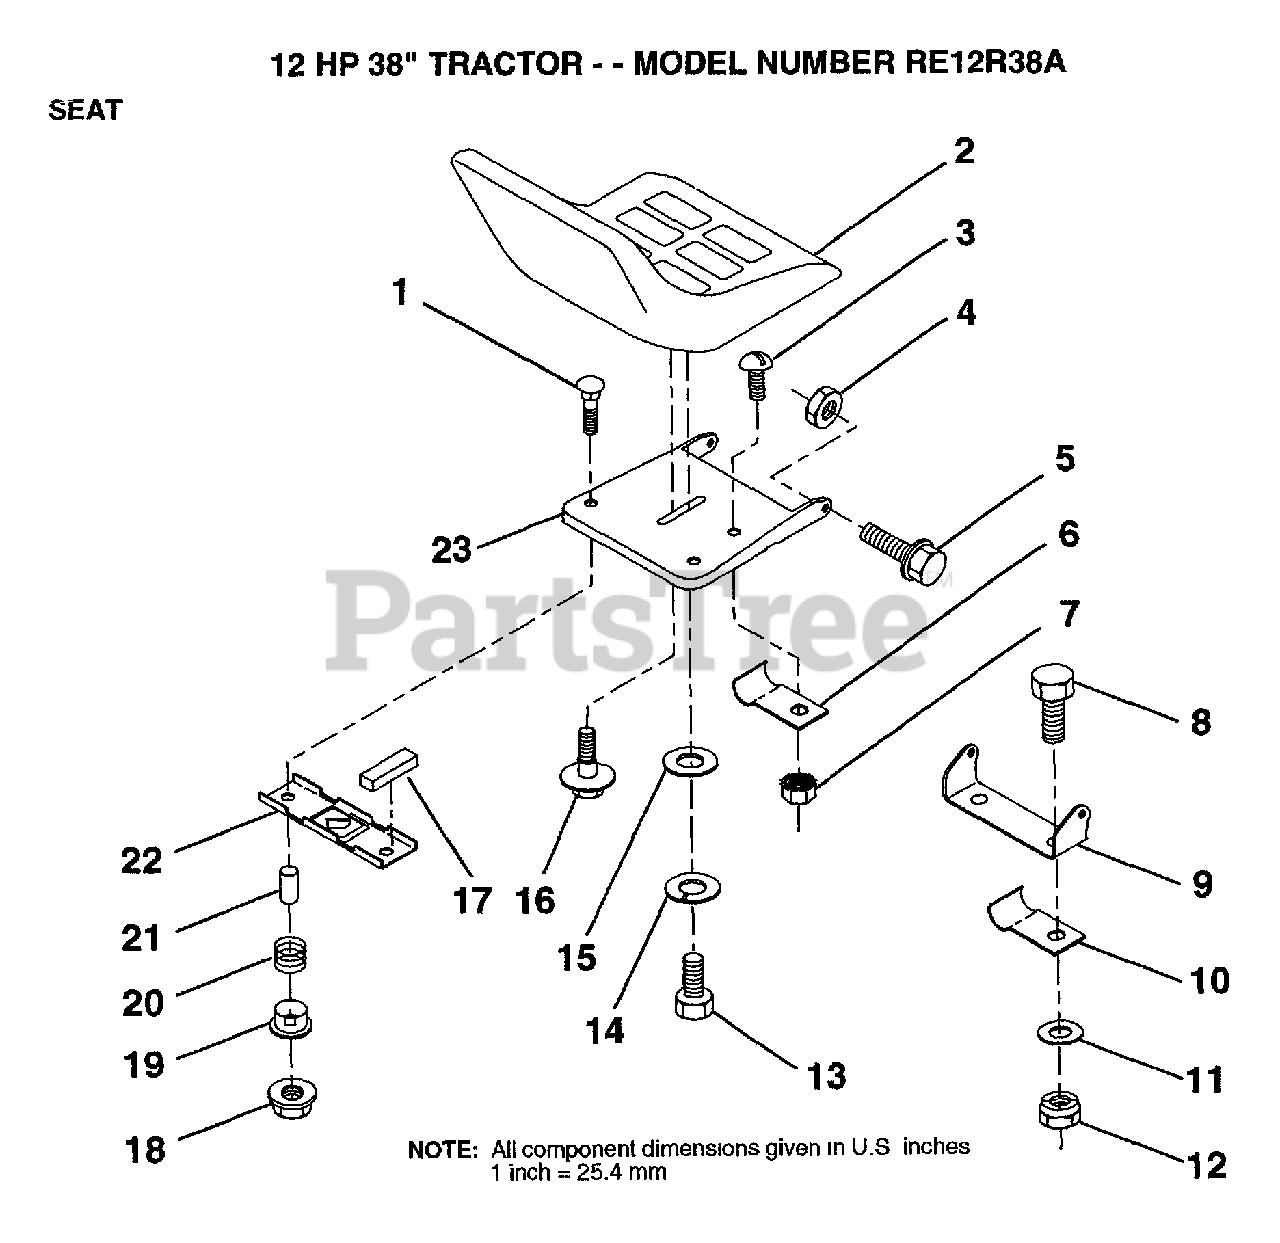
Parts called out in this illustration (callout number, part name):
5	Bolt Shoulder 5/16-18 Unc
6	CLIP T
7	"NUT,KEPS"
10	CLIP,INSULATOR
11	WASHER
13	BOLT
14	LOCKWASHER
15	WASHER
16	BOLT,SHOULDER
18	NUT.LOCK.1/4.LGE.FLG.GR.5
19	BUSHING
20	SPRING
21	SPACER SPLIT
22	BRKT SWITCH
